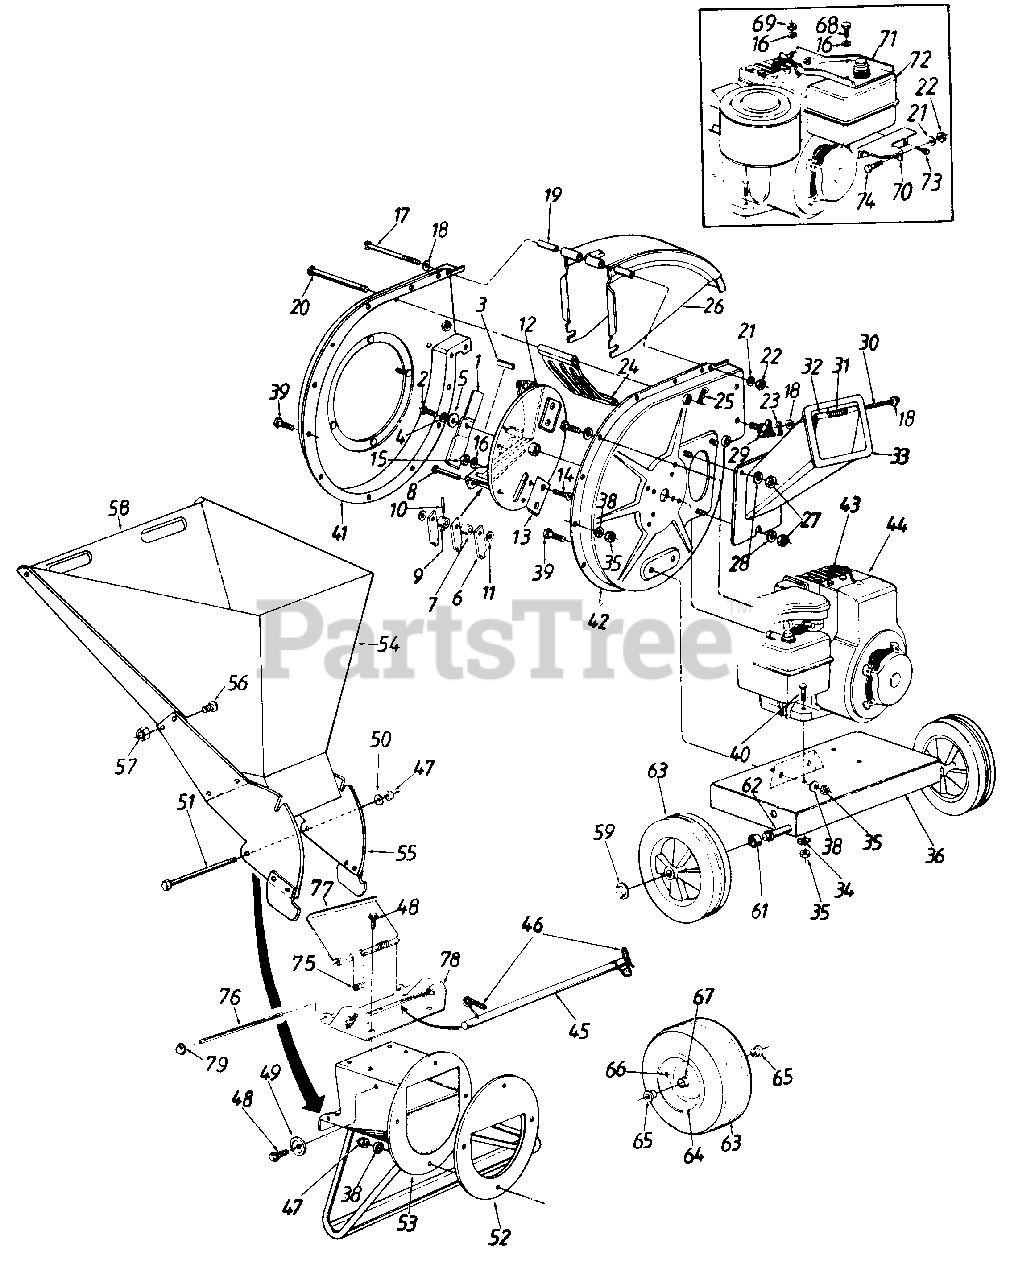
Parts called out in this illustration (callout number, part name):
3	Sq. Key 1/4 x 2.0" Lg.
4	L-Wash. 3/8" I.D. H.D.
5	Fl-Wash. .406" I.D. x 1.25" O.D. Hdn.
6	Flail
7	Flail Spacer
8	Clevis Pin .496" Dia.
9	Flail Spacer w/.160" Dia. Hole
10	Spring Roll Pin 1.12" Lg.
11	Fl-Wash. .531" I.D. x .94" O.D.
12	Impeller Ass'y.
13	Chipper Blade
14	Flat Hd. Scr. 5/16-24 x .75" Lg.
15	Hex Nut 5/16-24 (Grade 5)
16	L-Wash. 5/16" I.D.
17	Hex Bolt 1/4-20 x 4.0" Lg.
18	Fl-Wash. .281" I.D. x .5" O.D.
19	Chute Hinge Spacer 1.66" Lg.
20	Clevis Pin .5" Dia. x 4.62" Lg.
21	L-Wash. 1/4" I.D.
22	Hex Nut 1/4-20 Thd.
23	Cotter Pin
25	Internal Cotter Pin 3/8" Dia.
27	Hex Nut 5/16-18 Thd. (Grade 5)
28	Bell-Wash. .345" I.D. x .88"
29	Hand Knob
30	Chipper Door Rod
31	Torsion Spring 1.14" Lg.
35	Hex Nut 5/16-18 Thd. (Grade 5)
36	Shredder Frame
38	L-Wash. 5/16" I.D.
39	Hex Bolt 5/16-18 x .75" Lg. (Grade 5)
40	Hex Bolt 5/16-18 x 1.75" Lg.
43	Spark Plug Boot
44	Engine
45	Release Bar
46	Torsion Spring 1.06" Lg.
47	Elastic Lock Nut 5/16-18 Thd.
48	Hex Wash. Hd. Self-Tap Scr. 5/16-18 x .75" Lg.
49	Stop Washer
50	Fl-Wash. 5/16" I.D.
51	Hex Bolt 5/16-18 x 8.38" Lg.
52	Back-Up Plate
53	Inlet Guide Ass'y.
56	Truss Mach. Scr. 1/4-20 x .5"
57	Hex L-Nut 1/4-20 Thd.
61	Spacer .64" I.D. x .38" Lg.
62	Shredder Axle
63	Wheel Ass'y. Comp.
64	Rim Only
65	Flange bearing .632" I.D.
66	Air Valve
67	Grease Fitting
68	Hex Bolt 5/16-18 x .625"
69	Hex Nut 5/16-18 Thd. Gr. 5
70	Tank Support Brkt.
73	Hex Self-Tap Scr. #8 x .5"
74	Hex Bolt 1/4-20 x .62"*
75	Part Specification Not Listed
76	Part Specification Not Listed
77	Part Specification Not Listed
78	Part Specification Not Listed
79	Part Specification Not Listed
